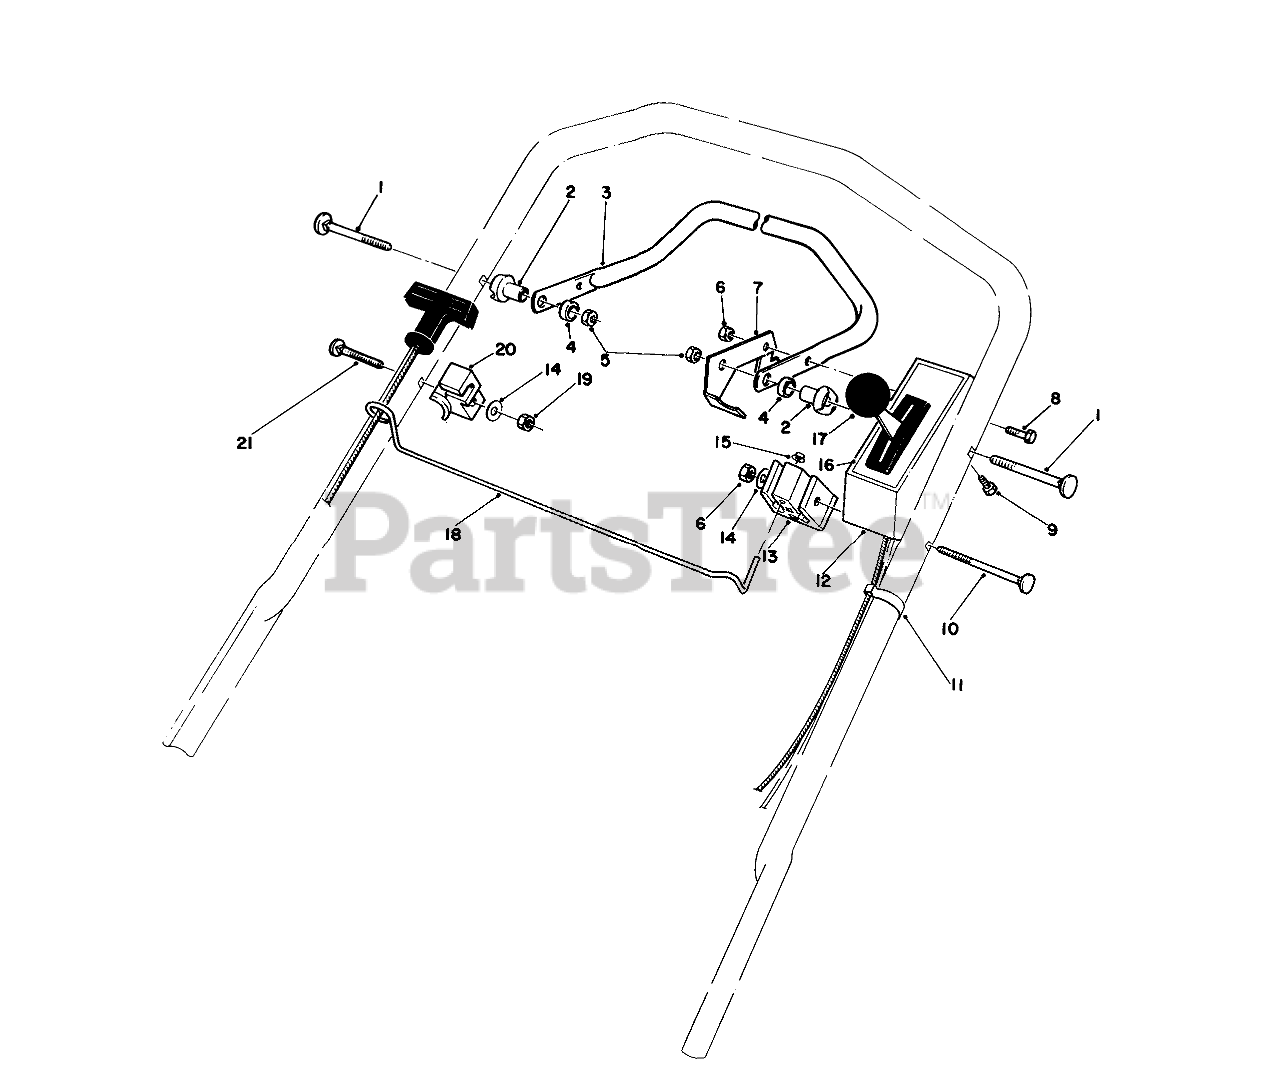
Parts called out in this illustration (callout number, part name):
1	5/16-18 X 2 HNDLE SCREW
2	SPACER-SUPPORT
3	Bar-Control
4	SPACER-NYLON
5	NUT-LOCK, NI
6	NUT-LOCK, NI
7	Lever-Control
8	SCREW-HH
9	SCREW-HWHTF
10	HANDLE SCREW
11	BOWDEN CLIP
12	Cover-Control (Incl. Ref. #16)
13	SUPPORT-CABLE
14	WASHER-FLAT
15	NUT-SPEED
16	Decal-Control Cover
17	SERVICE THROTTLE CONTRO
18	ROPE ROD PLATED
19	NUT-HEX
20	ROD CATCH
21	SCREW-HANDLE
